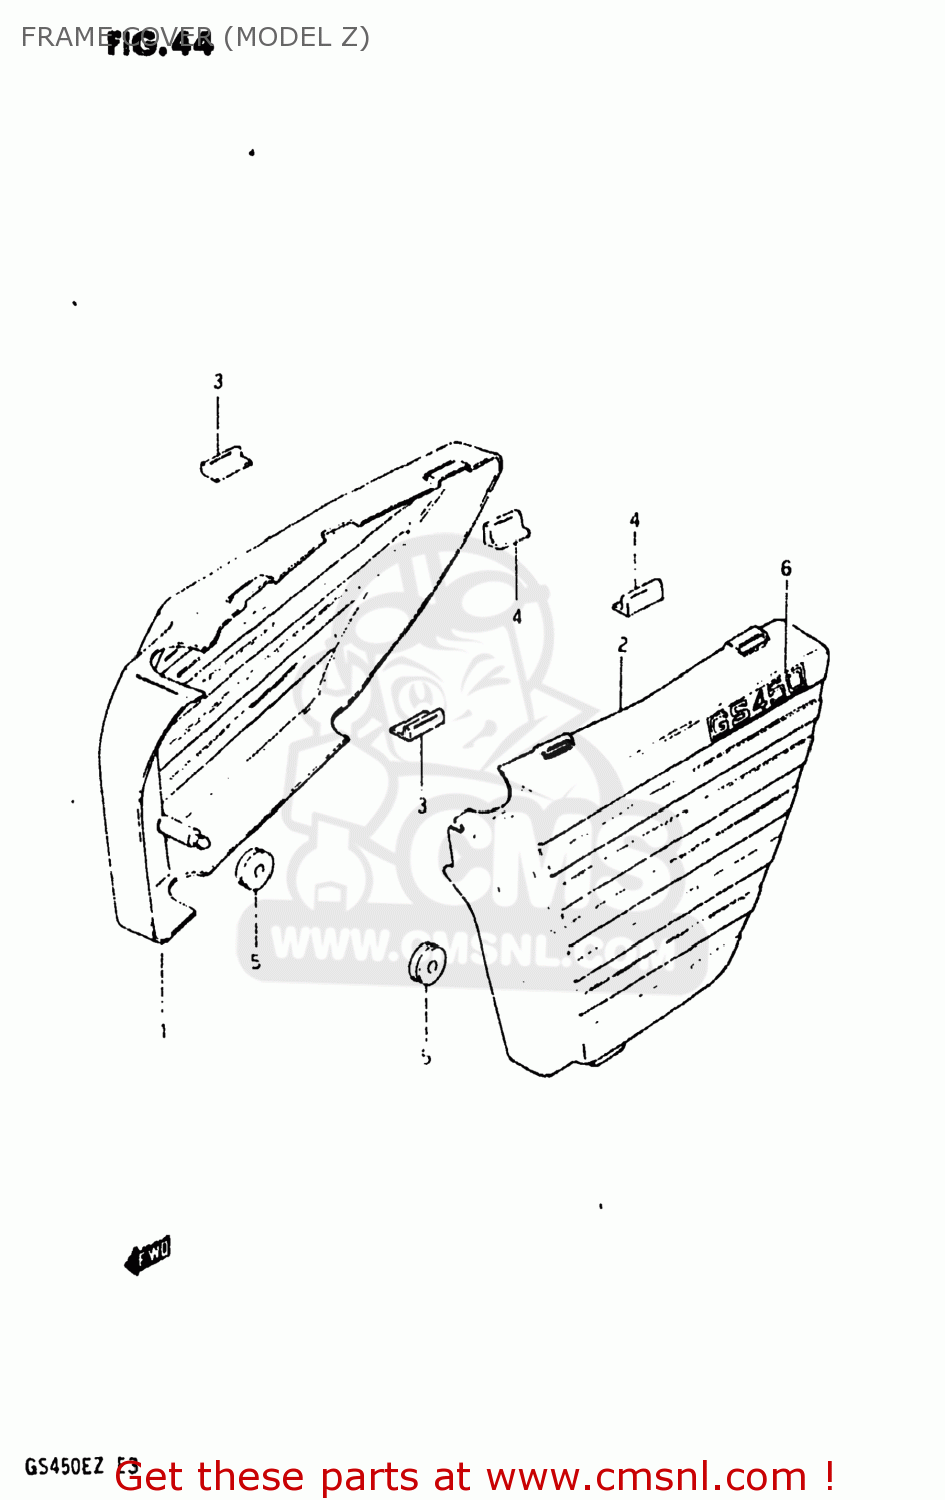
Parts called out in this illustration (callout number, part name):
1	COVER,FRAME,RIGHT
2	COVER,FRAME,LEFT
3	CUSHION,FRAME COVER
4	CUSHION,FRAME COVER
5	CUSHION
6	EMBLEM (450)
